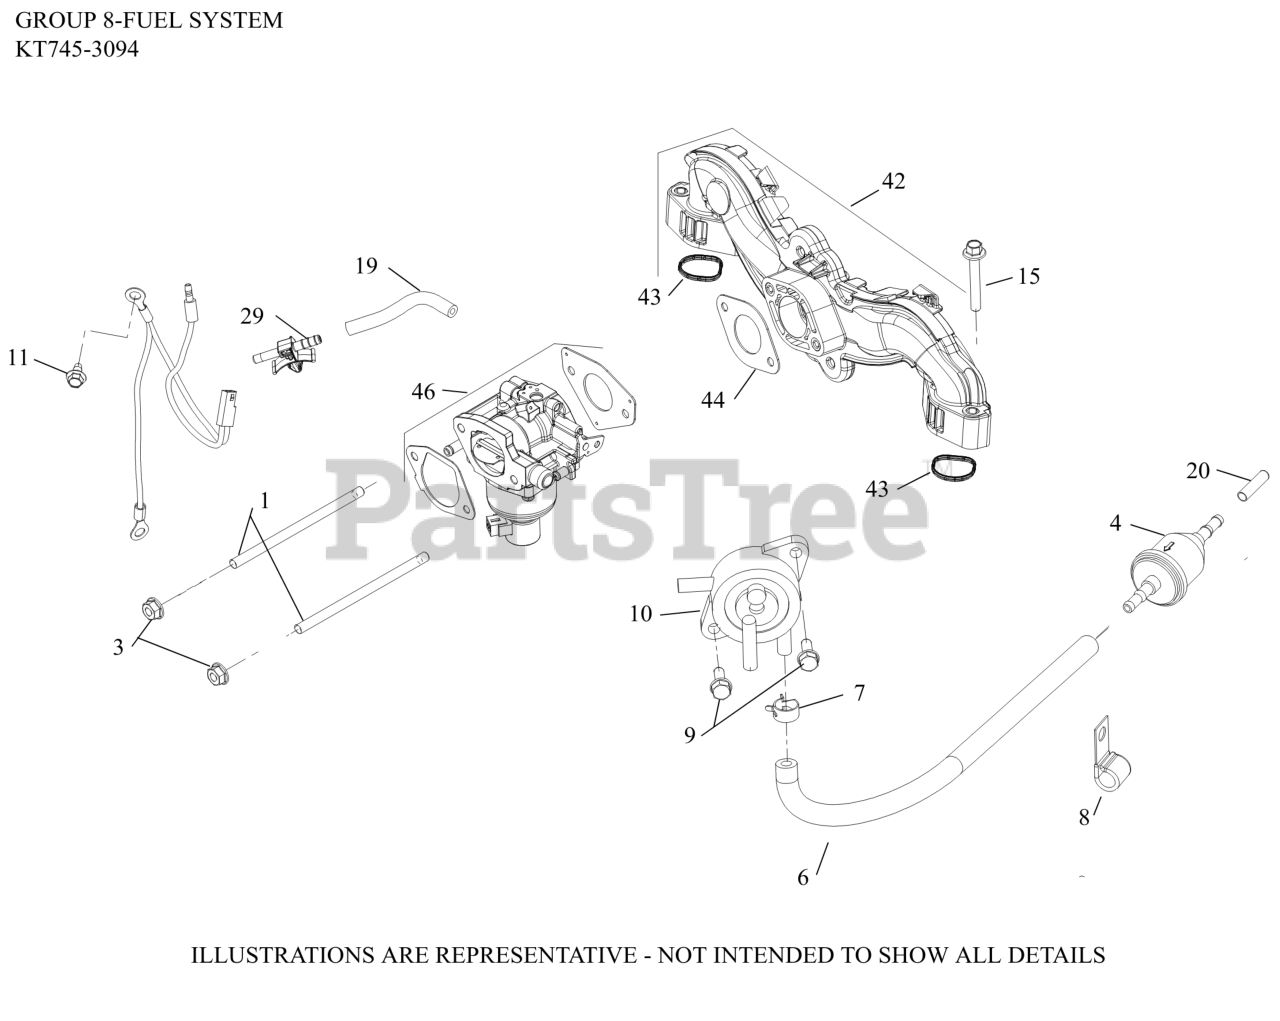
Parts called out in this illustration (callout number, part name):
3	NUT, FLG M6X1.0
4	FILTER,FUEL 51 MICRON (FUEL PUMP)
6	HOSE,LW PERM.FUEL 24.00"-USE 25 111 81-S
7	SPRING CLAMP, HOSE
8	CLIP, CABLE (KM)
9	SCREW, TAP M6X1.7X18
10	PUMP, FUEL (PULSE)-(#2539326S)
11	SCREW, THREAD FORMING
15	SCREW, FLG M6X1.0X40
19	HOSE EVAPORATIVE (WALBRO)
20	CAP, MASKING
29	CONNECTOR, EVAPORATIVE
42	INTAKE MANIFOLD W/GASKETS
43	O-RING, INTAKE PORT
44	GASKET, CARBURETOR (PIM, CV)
46	KIT,CARB(NIKKI)
NI	KIT, BOWL WITH O-RINGS NIKKI G-TYPE TWIN
NI	KIT, FLOAT AND NEEDLE NIKKI G-TYPE TWIN
NI	KIT,CHOKEREPAIR(SELF REL.)NIKKI G-TYPE T
NI	KIT, O-RING
NI	KIT, SOLENOID (NIKKI)
NI	KIT, HIGH ALTITUDE 5000 FT.
